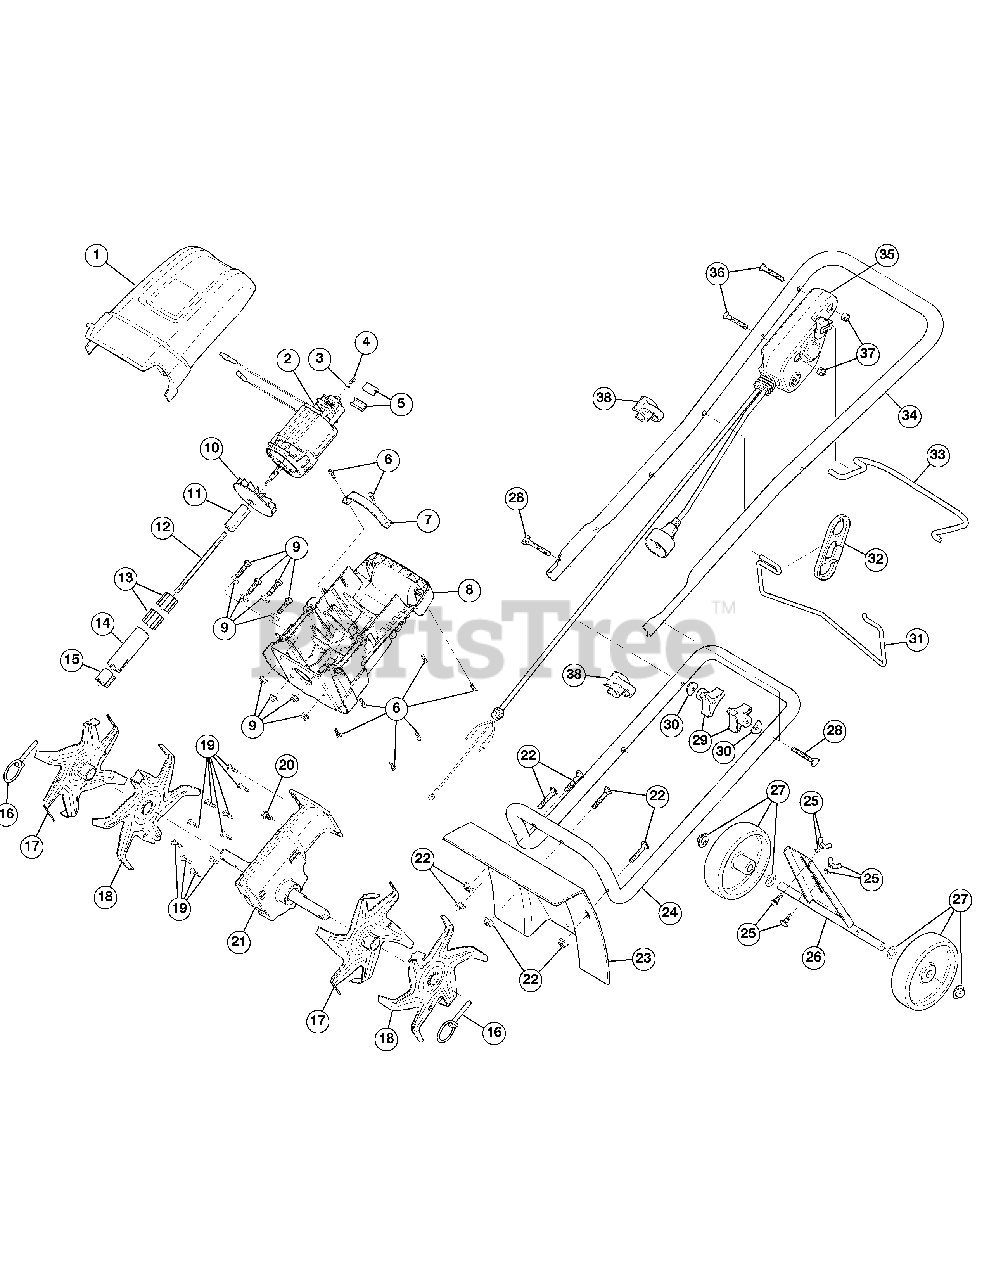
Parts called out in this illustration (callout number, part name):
1	Front Motor Cover
2	Motor Assembly
3	Lock Washer
5	Motor Pad
7	Motor Strap
8	Rear Motor Cover
9	Guard Mounting Hardware
11	Motor Hub
12	Flex Shaft
13	Flex Tube Assembly
14	Boom Tube
15	Sleeve
16	Click Pin
17	Tine Assembly
18	Tine Assembly
20	Sleeve Retainer Bolt
21	Gear Box Assembly
22	Handle Bar Mounting Hardware (Lower)
24	Lower Handle Bar
25	Wheel Bracket Mounting Hardware
26	Wheel Bracket Assembly
27	Wheel Assembly
30	Washer
31	Guide Bar
32	Cord Restraint
34	Upper Handle Bar
35	Switch Assembly
37	Nut
38	Cable Guide
